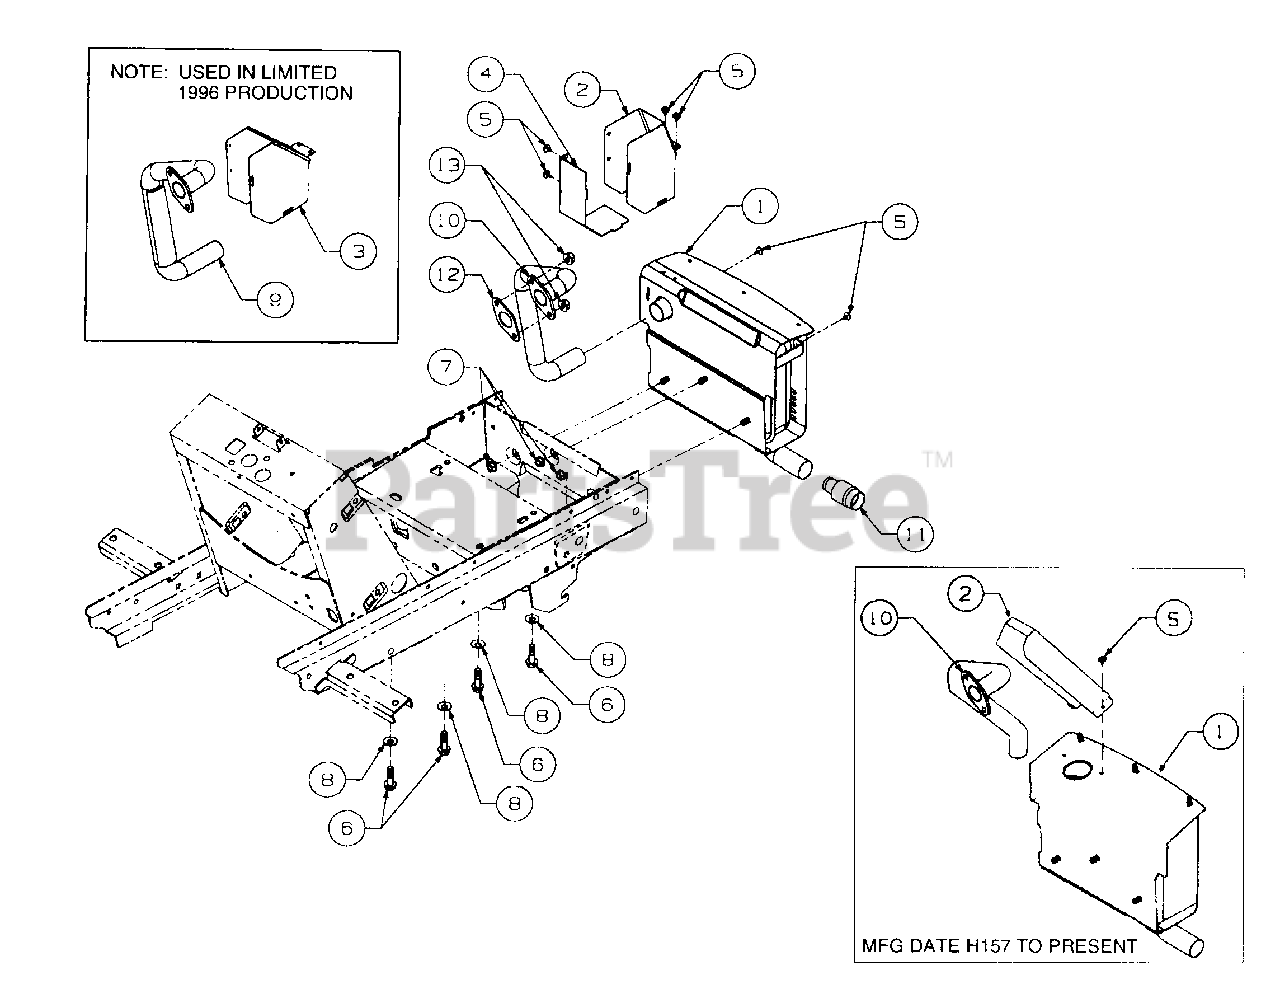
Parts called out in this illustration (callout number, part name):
1	Muffler Assy
2	Shield, Exh.
3	Shield, Exh
4	Shield, Exhaust Tube Rear
5	Screw, Hex Wash Hd Tapp, #10-16 x .38
6	Screw, Engine Mounting, 3/8-16 x 1.25
7	Nut, Hex Flange Lock, 5/16-18
8	Washer, Bell, .380 x .88 x .062
9	Tube, Exhaust, w/Attached Heat Baffle
10	Tube, Exh.
11	Arrestor, Spark
12	Gasket, Exhaust
13	Nut, Exhaust, M8 x 1.25
